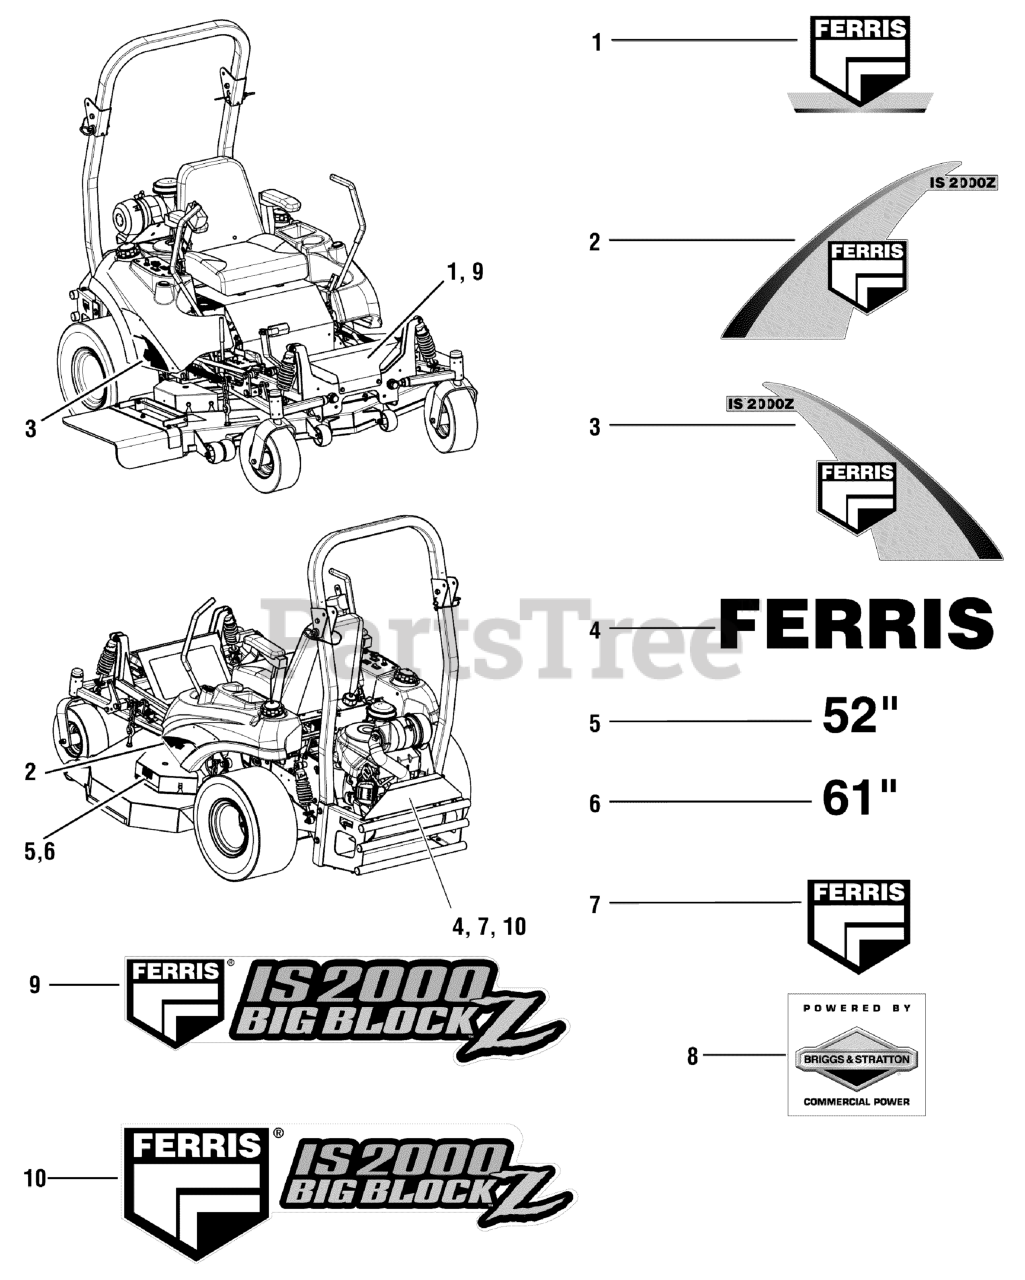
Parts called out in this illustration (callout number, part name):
2	DECAL, BADGE, IS2000Z, LH
3	DECAL, BADGE, IS2000Z, RH
4	DECAL, FERRIS TEXT
5	DECAL, 52
6	DECAL, 61"
9	DECAL, 2000, BIG BLOCK, FRONT
10	DECAL, 2000, BIG BLOCK, REAR
